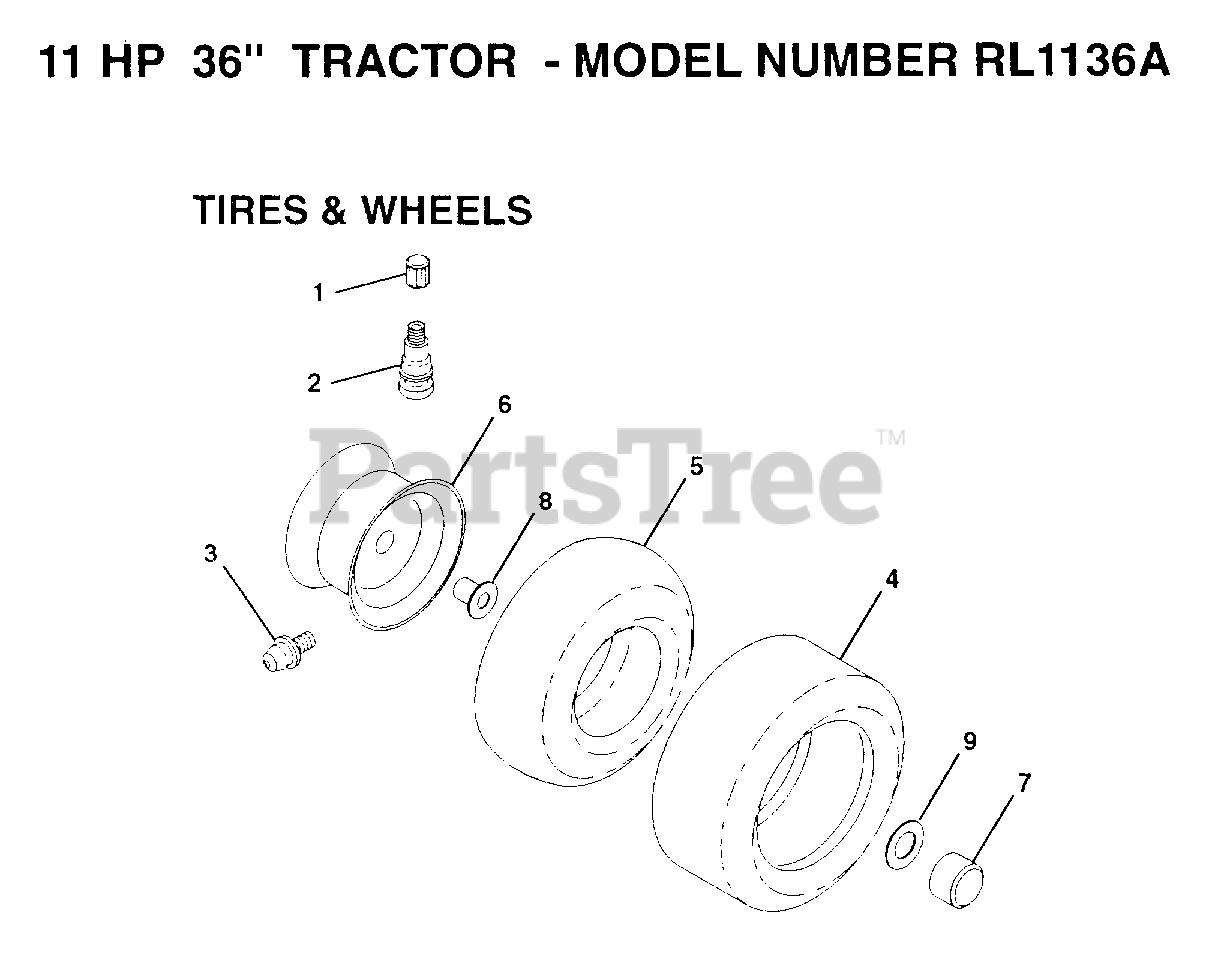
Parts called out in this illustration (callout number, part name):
1	VALVE CAP
2	VALVE STEM LT
3	FITTING LT
4	TIRE
5	TUBE.5.3/4.5/6
7	HUB CAP
8	"FLANGE, BEARING"
9	WASHER
